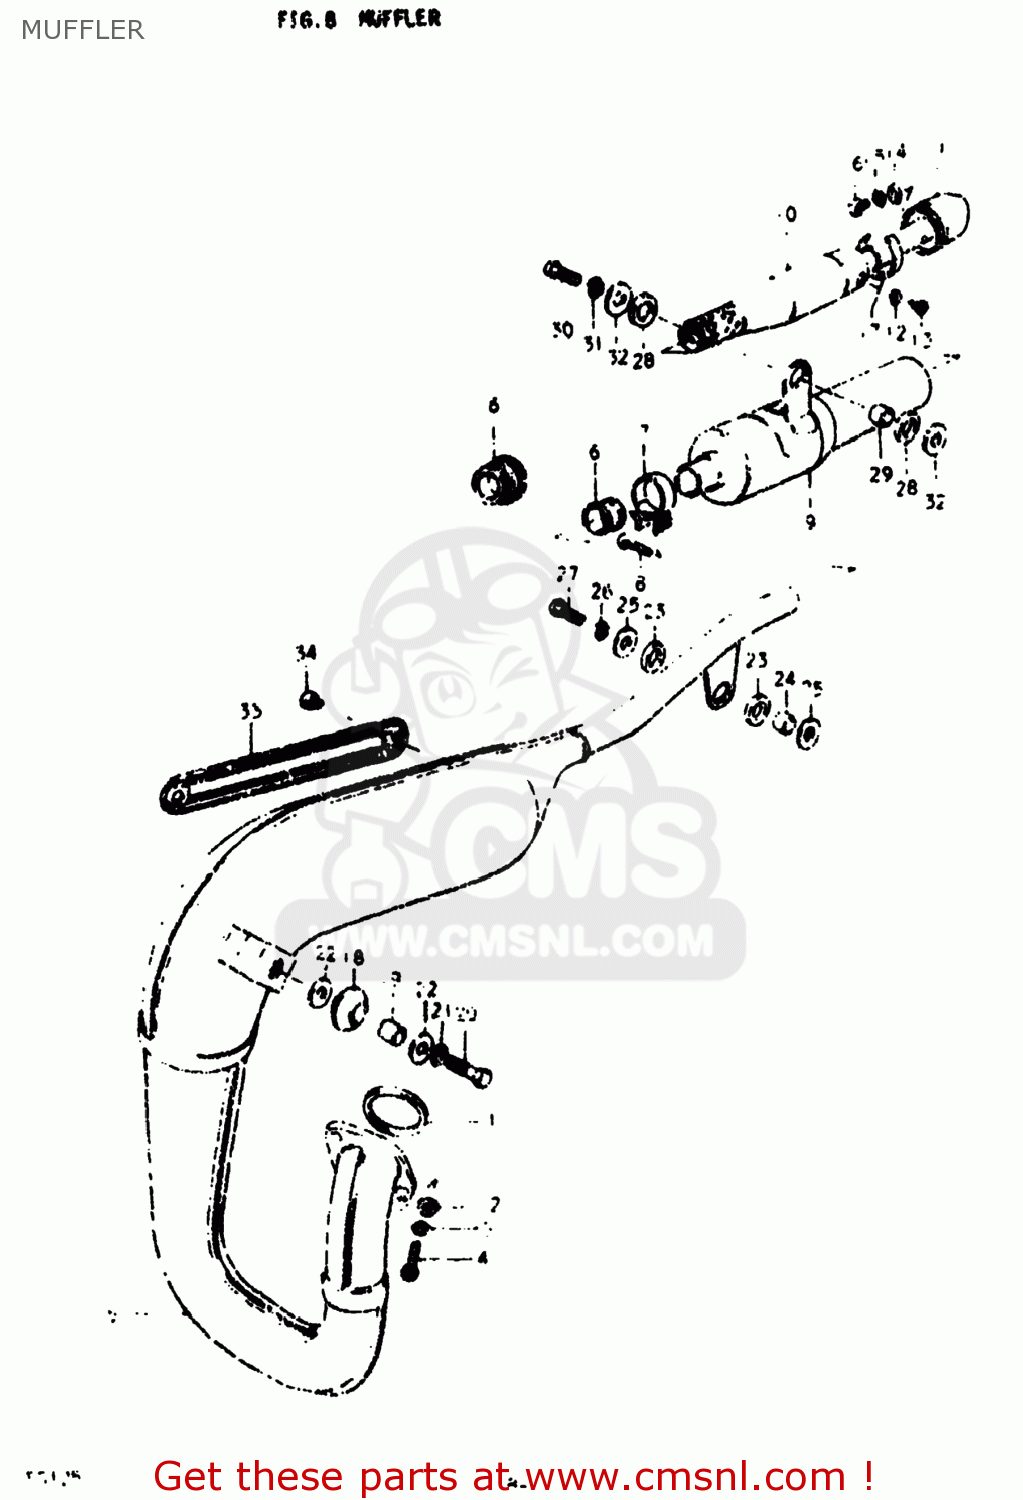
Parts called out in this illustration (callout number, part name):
1	GASKET,EXHAUST PIPE (NAS)
2	WASHER
3	LOCK WASHER
4	SCREW
5	BODY,MUFFLER
6	CONNECTOR,MUFFLER
7	CLAMP
8	SCREW
9	MUFFLER ASSEMBLY
10	ARRESTER,SPARK
11	TUBE,MUFFLER CLEAN OUT
12	LOCK WASHER
13	SCREW
14	WASHER
15	LOCK WASHER
16	SCREW(6X8)
17	BAND,SPARK ARRESTER
18	DAMPER,MUFFLER,FR
19	SPACER (8X12X15)
20	BOLT
21	LOCK WASHER
22	WASHER 8.2x27x2
23	WASHER
24	SPACER (8.6X13.8X9.8)
25	WASHER
26	LOCK WASHER
27	BOLT
28	CUSHION
29	SPACER (8.6X13.8X9)
30	BOLT
31	LOCK WASHER
32	WASHER
33	COVER,MUFFLER
34	SCREW
